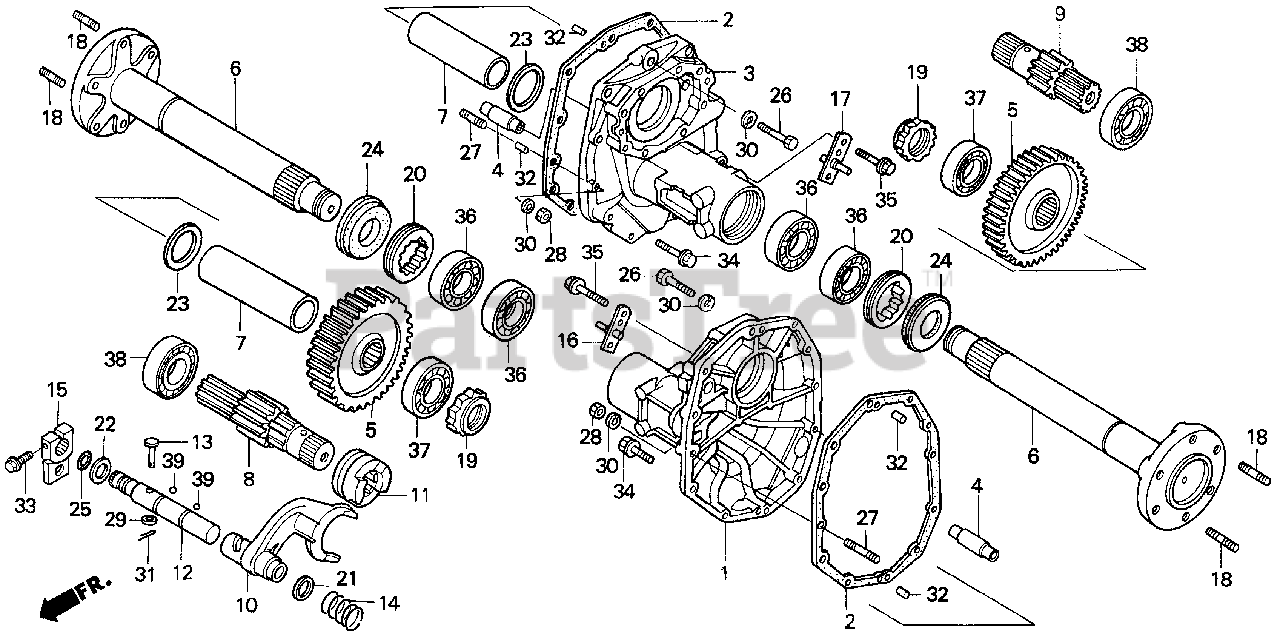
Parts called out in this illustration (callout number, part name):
1	HOUSING, R. RR. AXLE
2	GASKET, RR. AXLE HOUSING
3	HOUSING, L. RR. AXLE
4	PIPE, OIL GALLERY
5	GEAR, RR. FINAL DRIVEN
6	SHAFT, RR. AXLE
7	COLLAR, RR. AXLE
8	SHAFT, R. RR. DRIVE
9	SHAFT, L. RR. DRIVE
10	FORK, DIFFERENTIAL LOCK
11	SHIFTER, DIFFERENTIAL LOCK
12	SHAFT, DIFFERENTIAL LOCK
13	PIN, DIFFERENTIAL LOCK
14	SPRING, DIFFERENTIAL LOCK RETURN
15	ARM, DIFFERENTIAL LOCK
16	SHAFT, LINK (LOWER)
17	SHAFT, L. LINK (LOWER)
18	BOLT, STUD (16X25)
19	NUT, LOCK (35MM)
20	NUT, LOCK (78MM)
21	WASHER, THRUST (24MM)
22	WASHER (16MM)
23	WASHER, THRUST (45.2X60X2)
24	SEAL, WATER (45X81X13.8)
25	O-RING (13.5X1.5) (ARAI)
26	BOLT, HEX. (10X40)
27	BOLT, STUD (10X32)
28	NUT, HEX. (10MM) (NOT AVAILABLE)
29	WASHER, PLAIN (6MM)
30	WASHER, SPRING (10MM)
31	PIN, COTTER (2.0X15)
32	PIN, DOWEL (8X14)
33	BOLT, FLANGE (6X20)
34	BOLT, FLANGE (12X60)
35	BOLT, FLANGE (12X65)
36	BEARING, RADIAL BALL (6009)
37	BEARING, RADIAL BALL (6307)
38	BEARING, RADIAL BALL (6307)
39	BALL, STEEL (#4)
